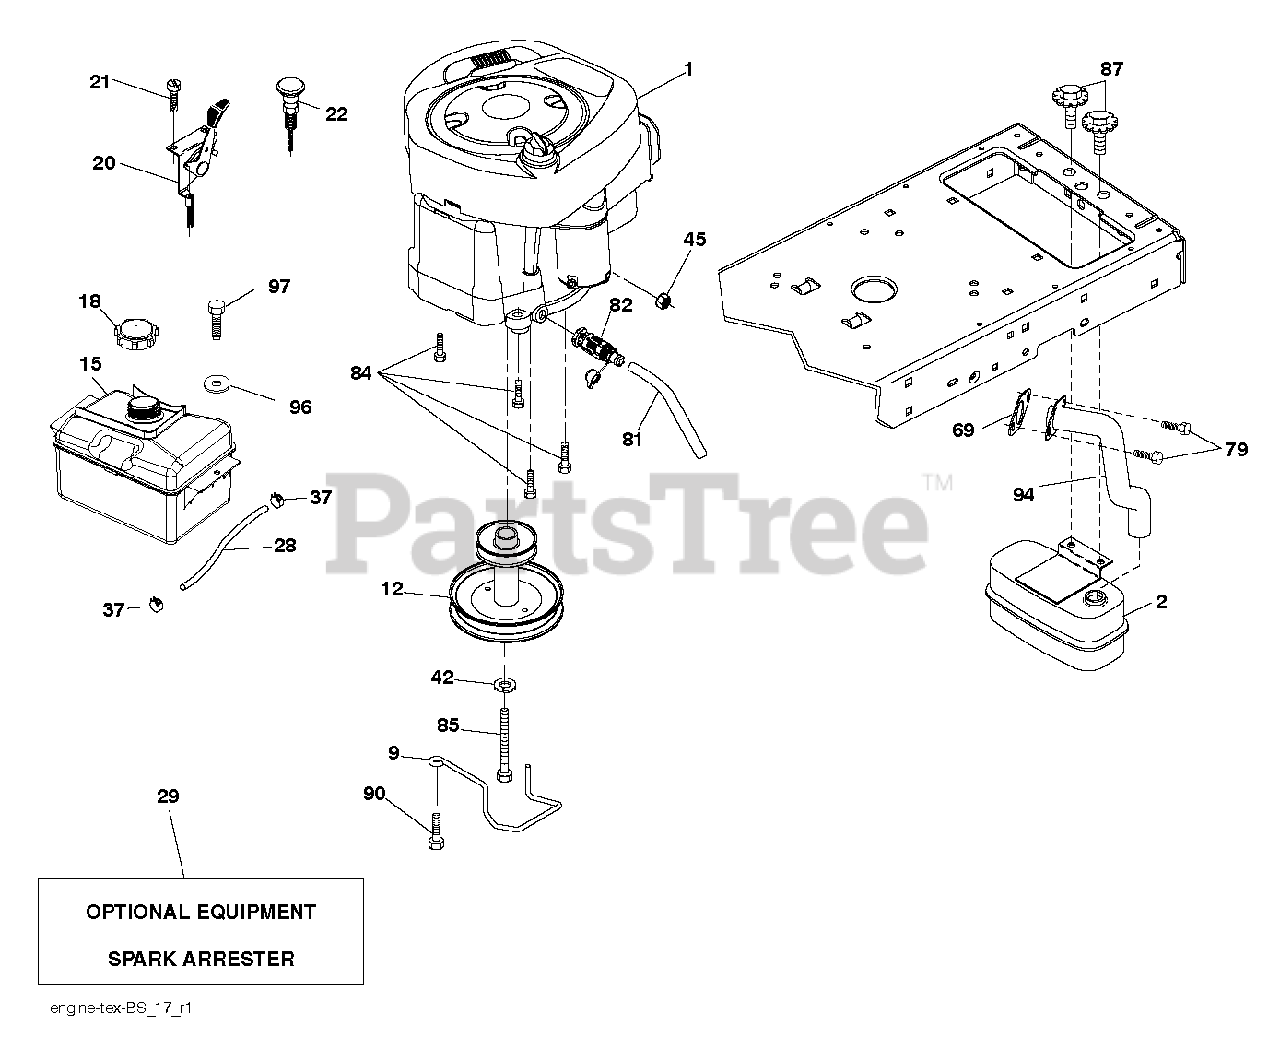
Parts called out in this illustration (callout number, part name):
2	MUFFLER.SINGLE.CYL.KOHL/B&S
9	KEEPER.BELT.ENGINE.4.2
12	PULLY ENGINE
15	TANK FUEL FRT 1.5 GAL
18	CAP ASM.FUEL.2.25"FR.
20	CONTROL.TH/CK.C.
21	SCREW.#10 X 0.750.BOS THREAD
28	LINE.FUEL.20
29	ARRESTER SPARK (OPTIONAL)
37	HOSE CLAMP
42	LOCKWASHER
45	NUT
69	REPL BY 532 27 22-93
79	SCREW.SOCKET HD.5/16-1
81	TUBE, DRAIN OIL ASM.
82	VALUE.OIL.DRAIN
84	SCREW.3/8-16
85	BOLT HEX 7/16-20X4-1/4"
87	BOLT, 5/16-18 X 1 3/4
90	SCREW 3/8-16X1
94	EXHAUST.TUBE.B&S.
97	SCREW HEXWSHR 1/4-20X3/4
